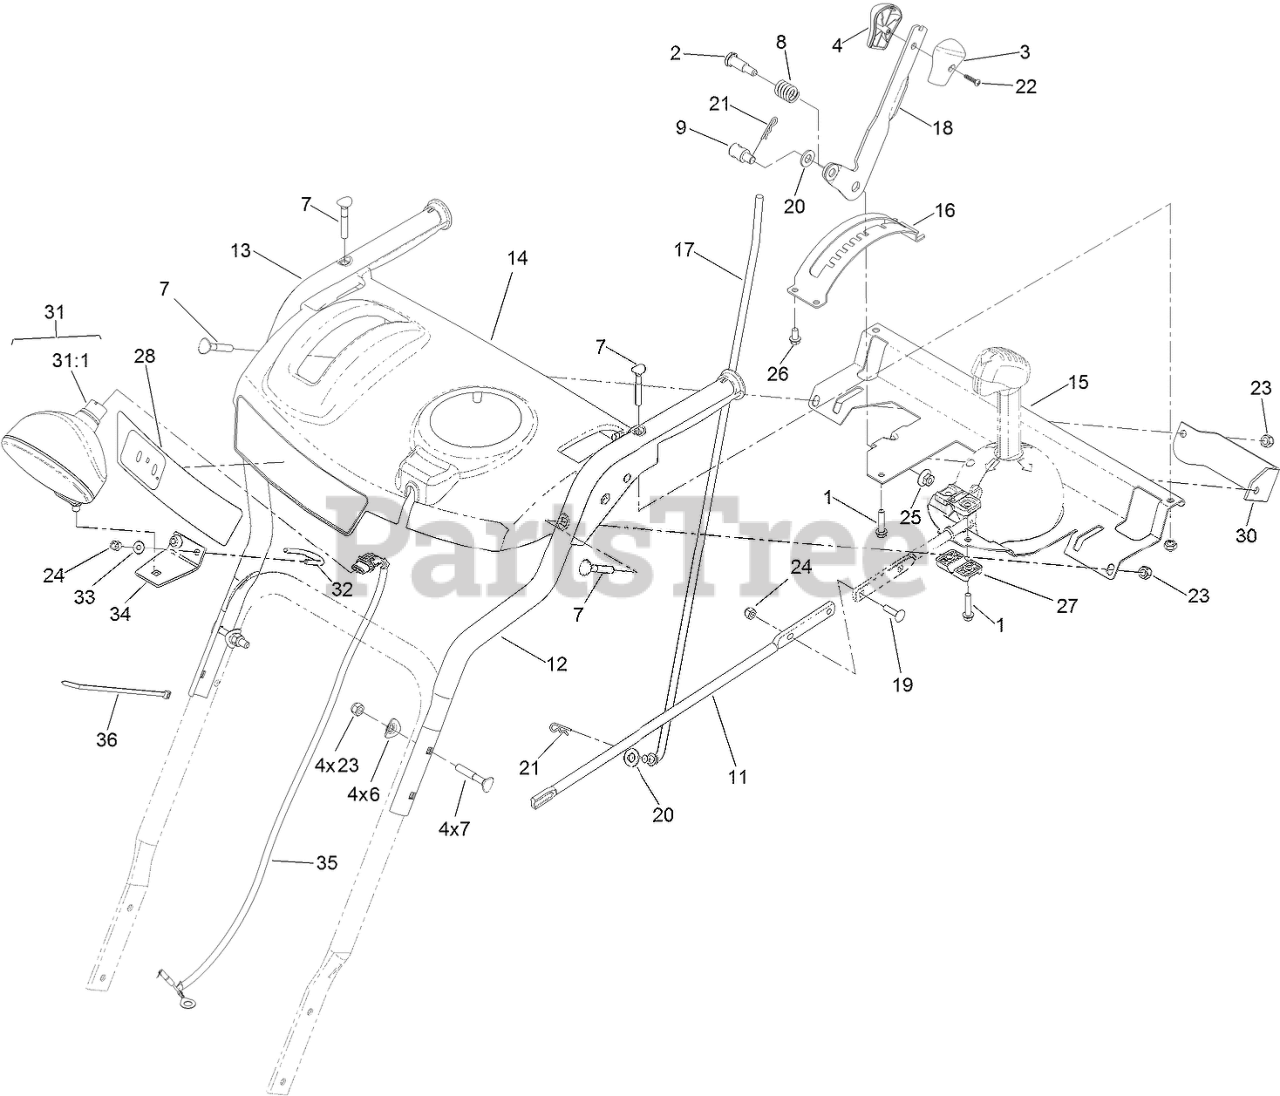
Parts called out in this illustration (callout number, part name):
1	SCREW-PLASTITE
2	SCREW-SHOULDER
3	KNOB-SHIFT, LH
4	KNOB-SHIFT, RH
6	WASHER
7	SCREW-HANDLE
8	SPRING-COMPRESSION
9	TRUNNION-ROD
11	ROD-CHUTE, FRONT
12	HANDLE-UPPER, LH
13	HANDLE-UPPER, RH
14	PANEL-CONTROL, MASTER
15	SUPPORT-PANEL, CONTROL
16	MOUNT-SELECTOR, SPEED
17	ROD-SELECTOR, GEAR
18	SELECTOR-SPEED
19	SCREW-CARR
20	WASHER-FLAT
21	PIN-COTTER
22	SCREW-PPH
23	NUT-LOCK, NI
24	NUT-LOCK, NI
25	NUT-HF
26	SCREW-PLASTITE
27	SUPPORT-ROD
28	DECAL-PANEL, CONTROL
30	PLATE-SUPPORT, SHIFT
31	HEADLAMP ASM
31:1	LAMP-12 VOLT
32	CLAMP
33	WASHER-FLAT
34	BRACKET-LIGHT
35	HARNESS-WIRE
36	TIE-CABLE
